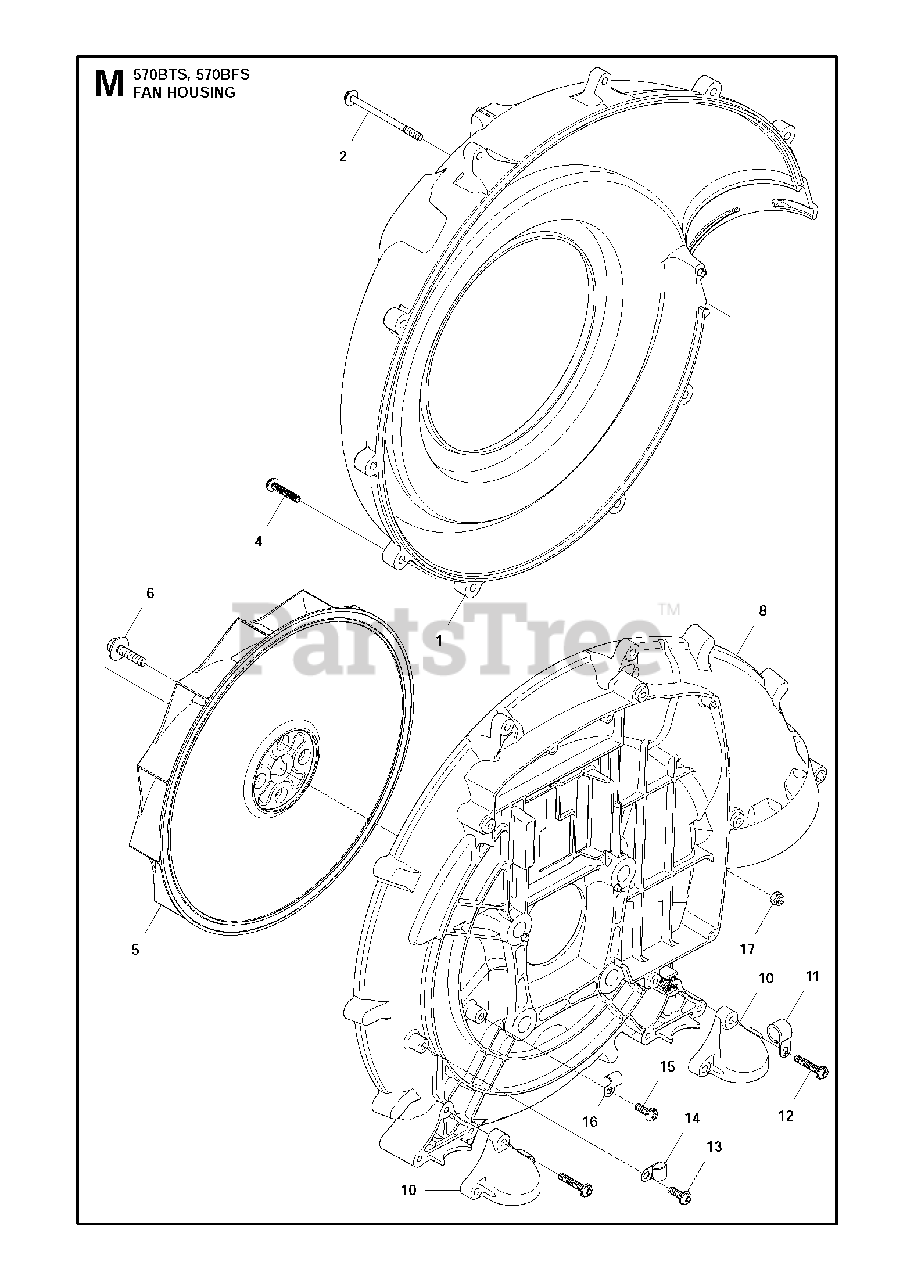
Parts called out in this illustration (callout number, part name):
1	COVER VOLUTE
5	FAN
8	CASE VOLUTE
10	BRACKET DAMPNER
14	CLAMP
16	CLAMP
